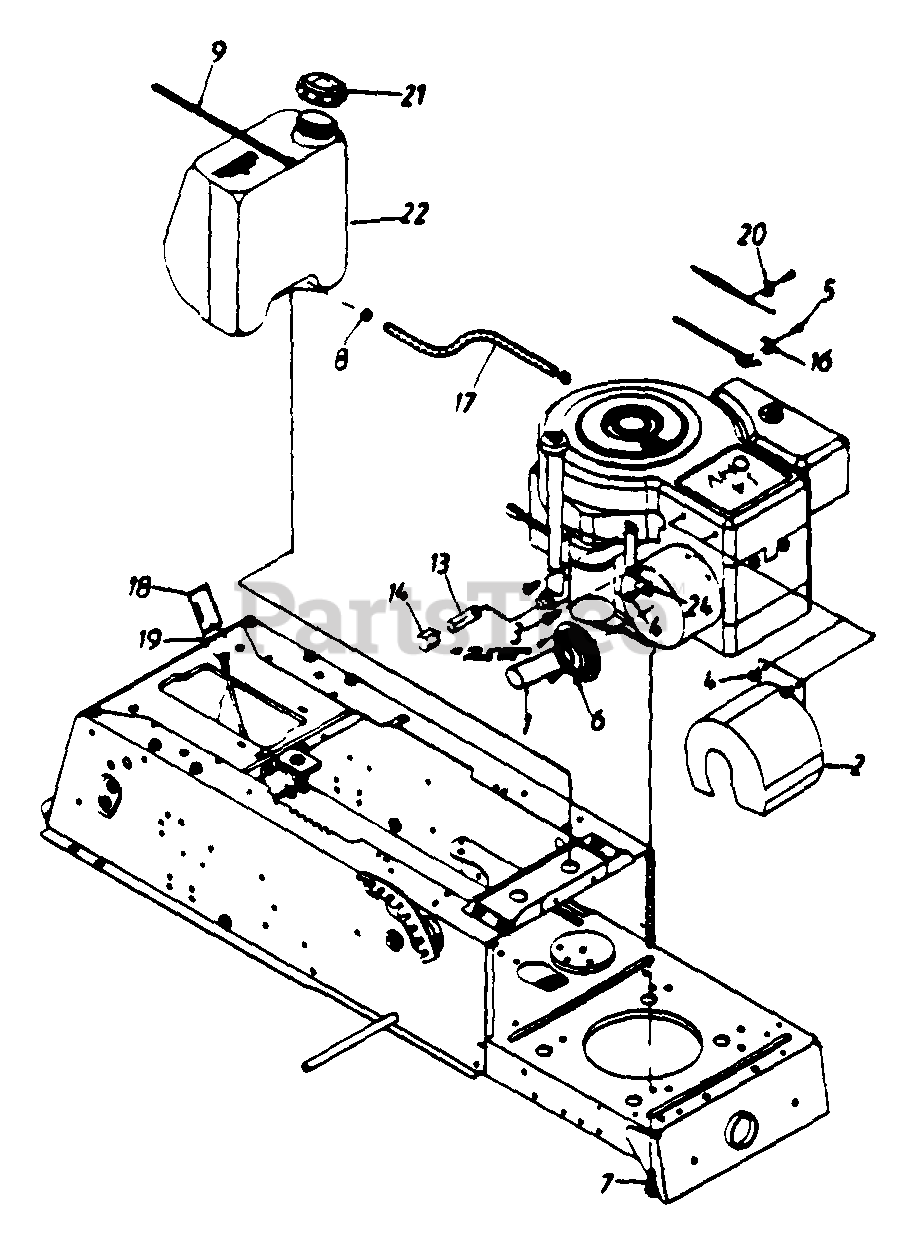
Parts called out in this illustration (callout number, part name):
1	Exhaust Pipe Ass'y.
2	Heat Shield Ass'y.
3	Pan Hd. Mach. Scr. 5/16-18 x 75"
4	Hex Wash. Hd. Scr. 1/4-20 x .5"
5	Hex Slot Wash. Hd. #10-32 x 5/8" Lg.
6	Hex Wash. Hd. F-Tap Scr. #8-32 x .38"
7	Hex L-Wash. TT-Tap Scr. 3/8-16 x 1.25"
8	Hose Clamp -.49" Dia.
9	Cable Tie-30.66" Lg.
13	Pipe Nipple 3/8-18 NPT x 2" Lg.
14	Cap - Oil Drain
16	Casing Clamp
17	Fuel Line Hose
20	Casing Clamp
21	Fuel Cap w/o Gasket
22	Gas Tank - 1-1/2 Gallon
24	Bracket Heat Shield
